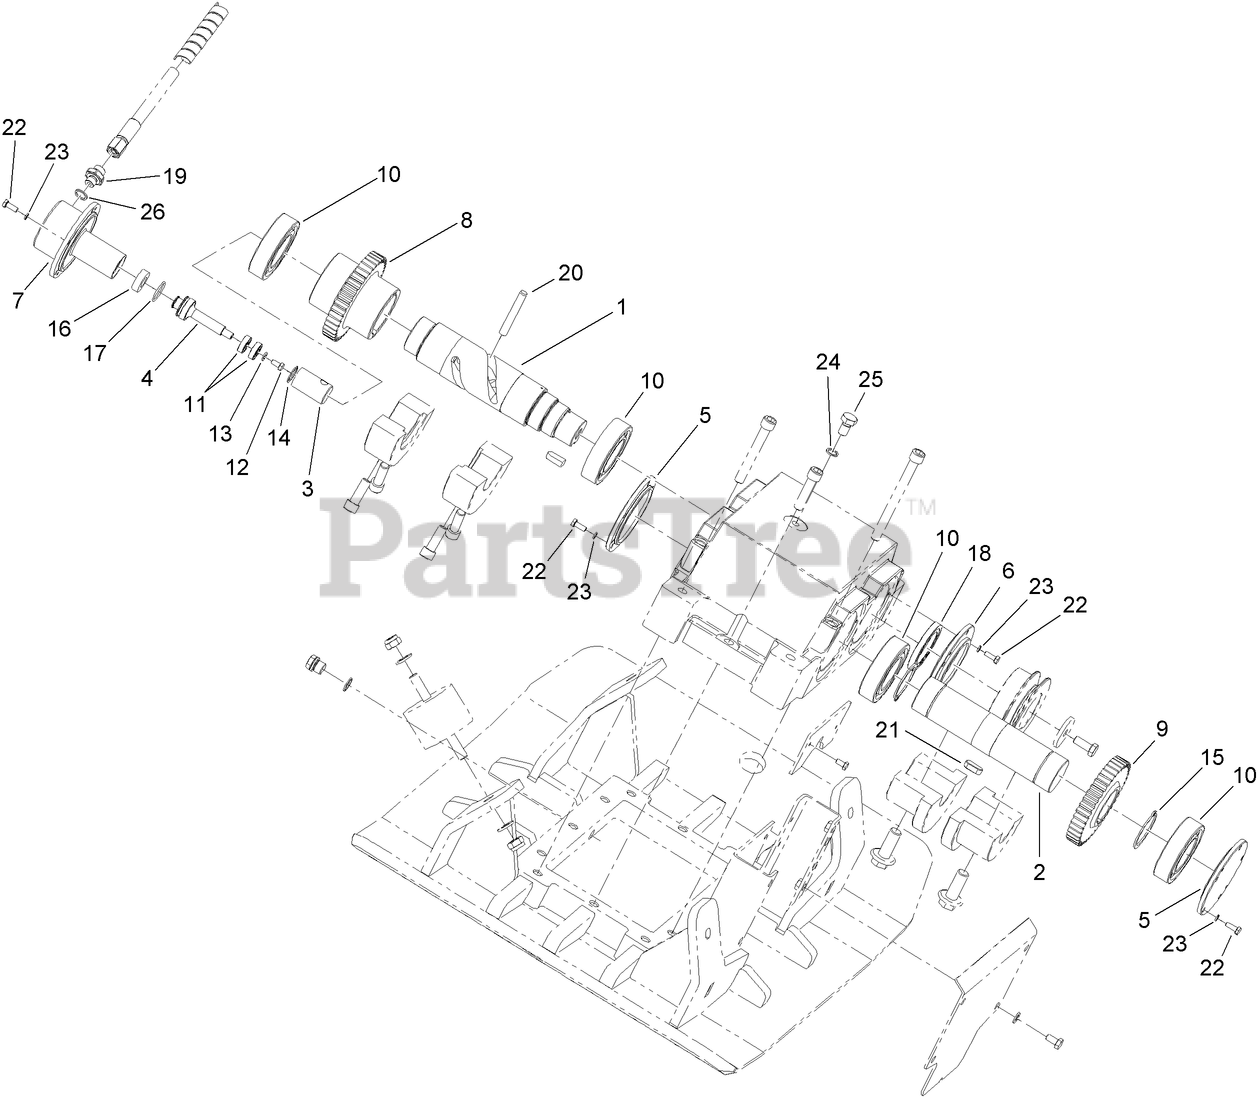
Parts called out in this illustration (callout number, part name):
1	SHAFT-HOLLOW
3	SLIDE-VALVE
4	PISTION
10	BEARING
11	BEARING
13	WASHER
16	SPACER
17	O-RING
18	SPACER
19	SOCKET
23	WASHER
24	RING-SEALING
26	RING-SEALING
